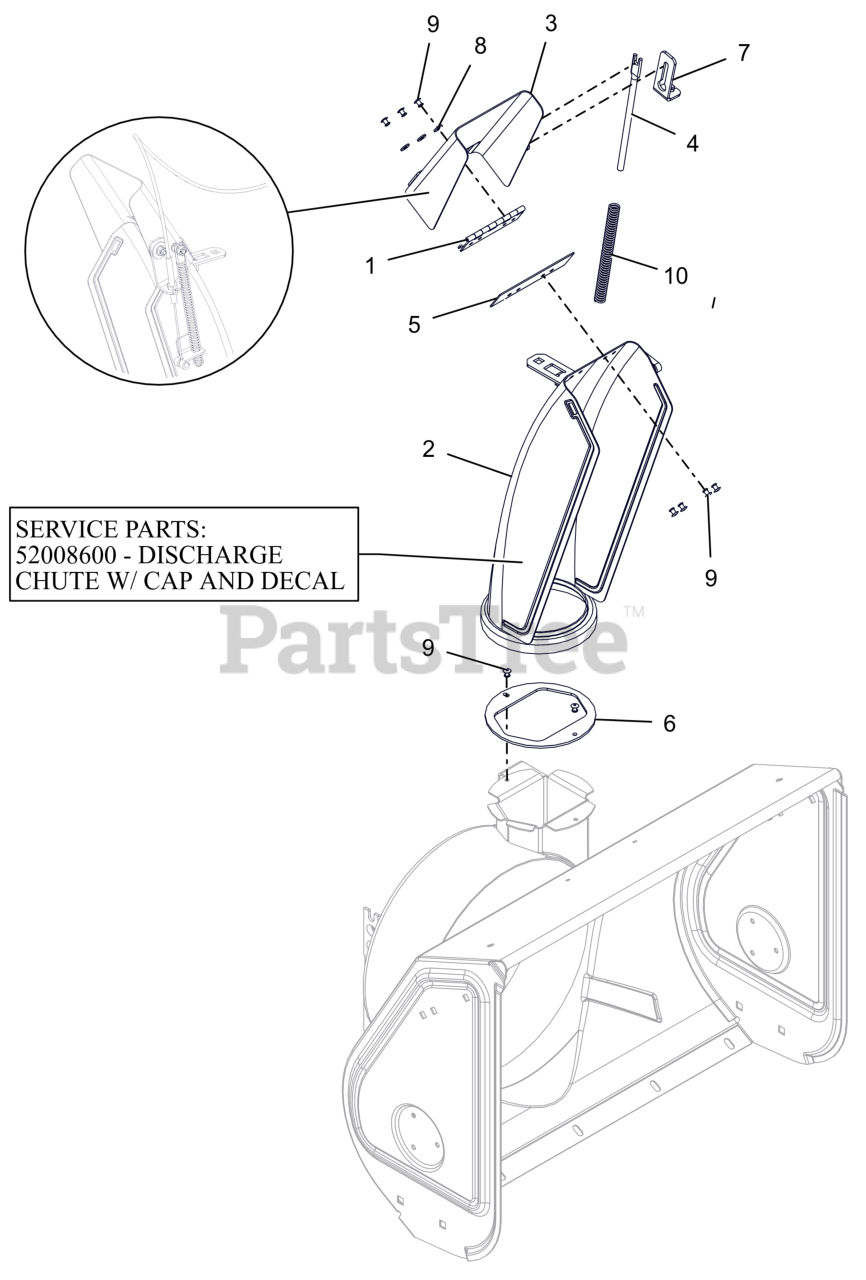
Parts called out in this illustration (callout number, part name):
2	CHUTE, COMPACT-TALL W/REMOTE
2	CHUTE, DISCHARGE W/CAP
3	CAP, REMOTE COMPACT W/DECAL
4	ROD, DEFLECTOR CAP
5	CAP SEAL 5.25
6	BAFFLE, COMPACT DISCHARGE
7	BRACKET, ANCHOR-CHUTE CABLE
8	WSHR,FLT .196X.500X.066 ZCC
9	RVT, POP .1875 ZCC
10	SG-COMP .08X.40X6.50 14#/IN
